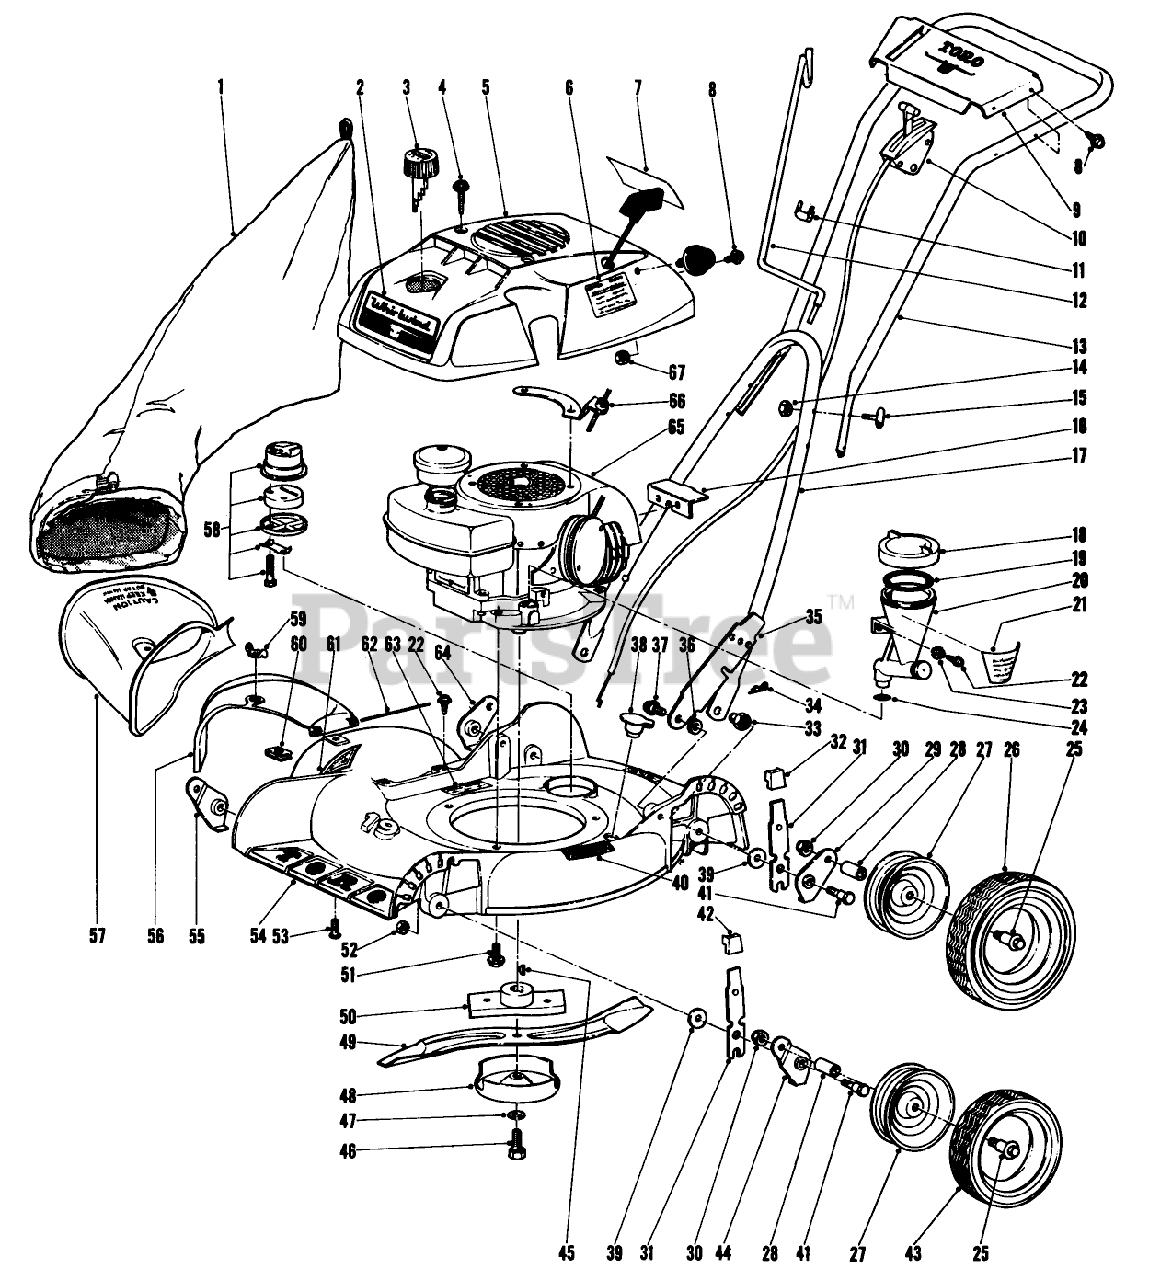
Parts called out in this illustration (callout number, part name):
1	Bag-Set of 2
2	Decal
3	Gas Cap
4	SCREW-HWH
5	Shroud
6	Decal-Start & Prime
7	Decal
8	SCREW-HWHTF
9	Escutcheon
10	Throttle Control
11	CONTROL WIRE CLIP
12	GRASS BAG HANGER
13	Handle-Upper
14	Nut
16	Bracket
17	Handle-Lower
18	Reservoir Cap w/Ring
19	"O" Ring
20	Reservoir, Oil
21	Decal, Reservoir
22	Screw
23	Washer
24	O-RING
26	8 TIRE
27	Wheel (Incl. Ref. 22)
28	Bushing
29	Pivot Arm
30	NUT-HEX
31	Spring Arm
33	Nut
34	PIN-COTTER, HAIR
35	Latch
36	SPACER
37	SCREW-SHOULDER
38	Washer Plug
39	Washer
41	5/16-18 PIVOT SCREW
42	ARM KNOB
44	Arm, Pivot
45	KEY-WOODRUFF
46	SPECIAL SCREW
47	WASHER-LOCK
48	Scalp Cup
49	Blade
50	BLADE RETAINER WA
51	Screw, Self Tapping
52	Nut
54	Housing
55	Arm, Pivot
56	Deflector
57	Attachment Bag
58	MUFFLER KIT
59	NUT-WING SPECL
60	NUT-SPEED
61	Decal
62	HINGE PIN
63	Decal
64	Pivot Arm
65	Engine, Recoil
66	Bracket,Recoil
67	NUT-KEPS
